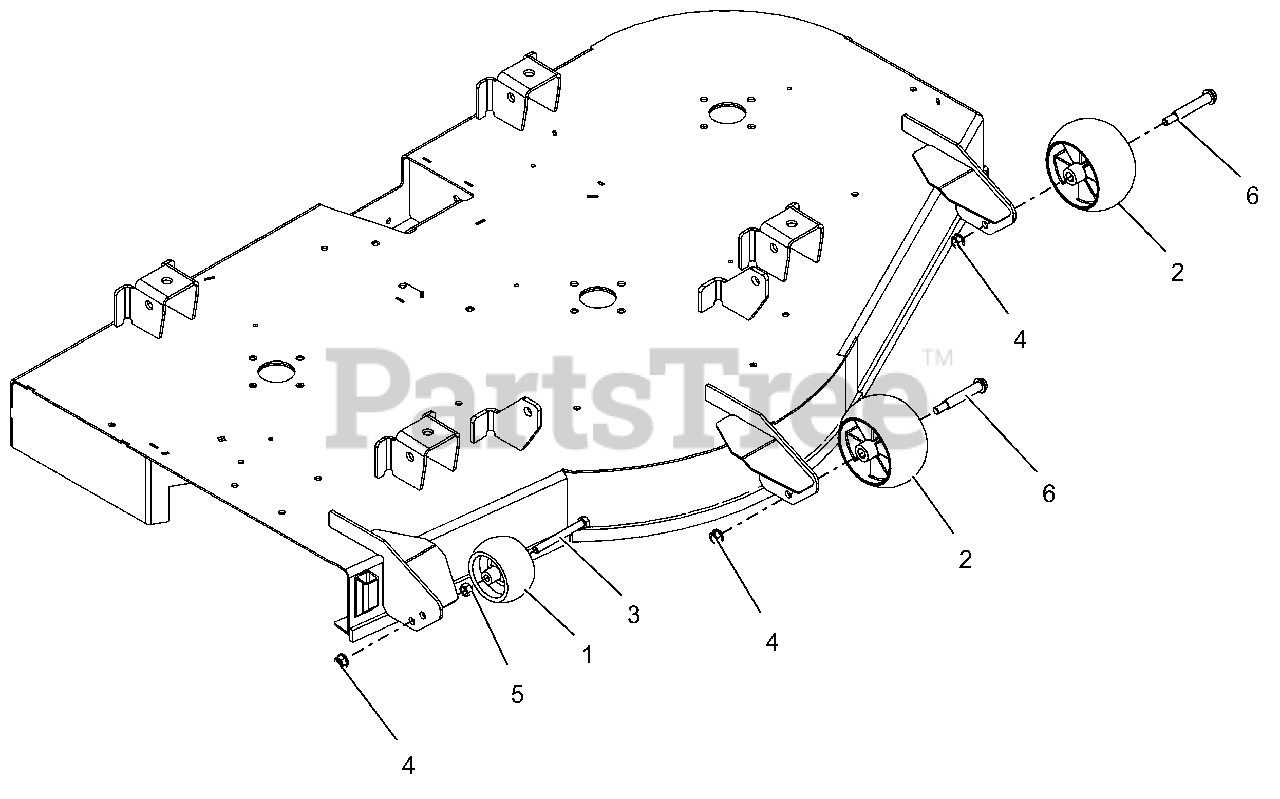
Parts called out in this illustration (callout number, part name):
2	ANTI-SCALP WHEEL - 5X OS
3	BLT, HEX .38-16X3.50 G5 ZCC
4	NUT-LK-CTR-FLG .375-16 GF ZCC
5	NUT-STD .375-16 G2 ZCC
6	BLT-SHLDR .38-16X2.50 HWH G5
